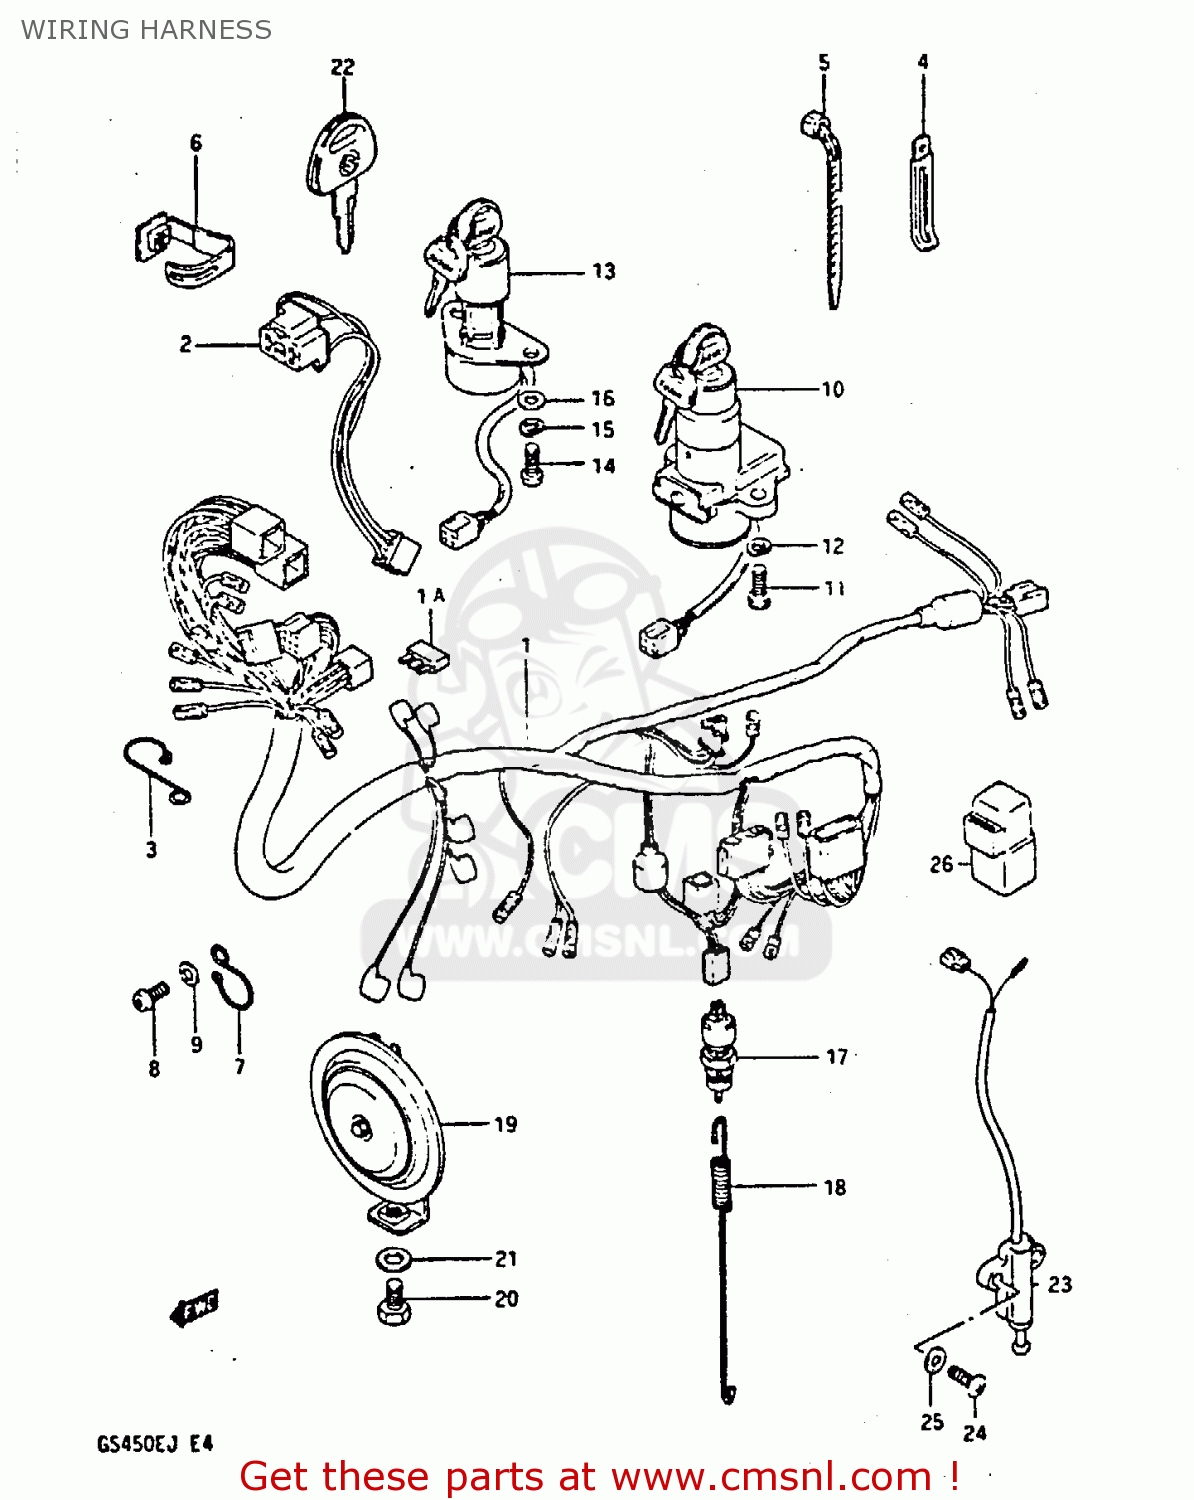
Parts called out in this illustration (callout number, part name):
1	WIRING HARNESS
1A	DIODE(STANLEY DE8804)
2	LEAD WIRE,HEADLAMP
3	CLIP,WIRING HARNESS
4	CLAMP
5	CLAMP(L:125)
6	CLAMP,WIRING HARNESS
7	CLIP,WIRING HARNESS
8	SCREW
9	WASHER
10	LOCK ASSEMBLY,STEERING
11	BOLT
12	WASHER,LOCK
13	SWITCH ASSY,IGNITION
14	SCREW
15	WASHER,LOCK
16	WASHER
17	SWITCH ASSY,STOP LAMP
18	SPRING
19	HORN
20	BOLT
21	WASHER
22	KEY,BLANK
23	SWITCH ASSEMBLY,SIDE STAND
24	SCREW
25	WASHER
26	RELAY ASSEMBLY
